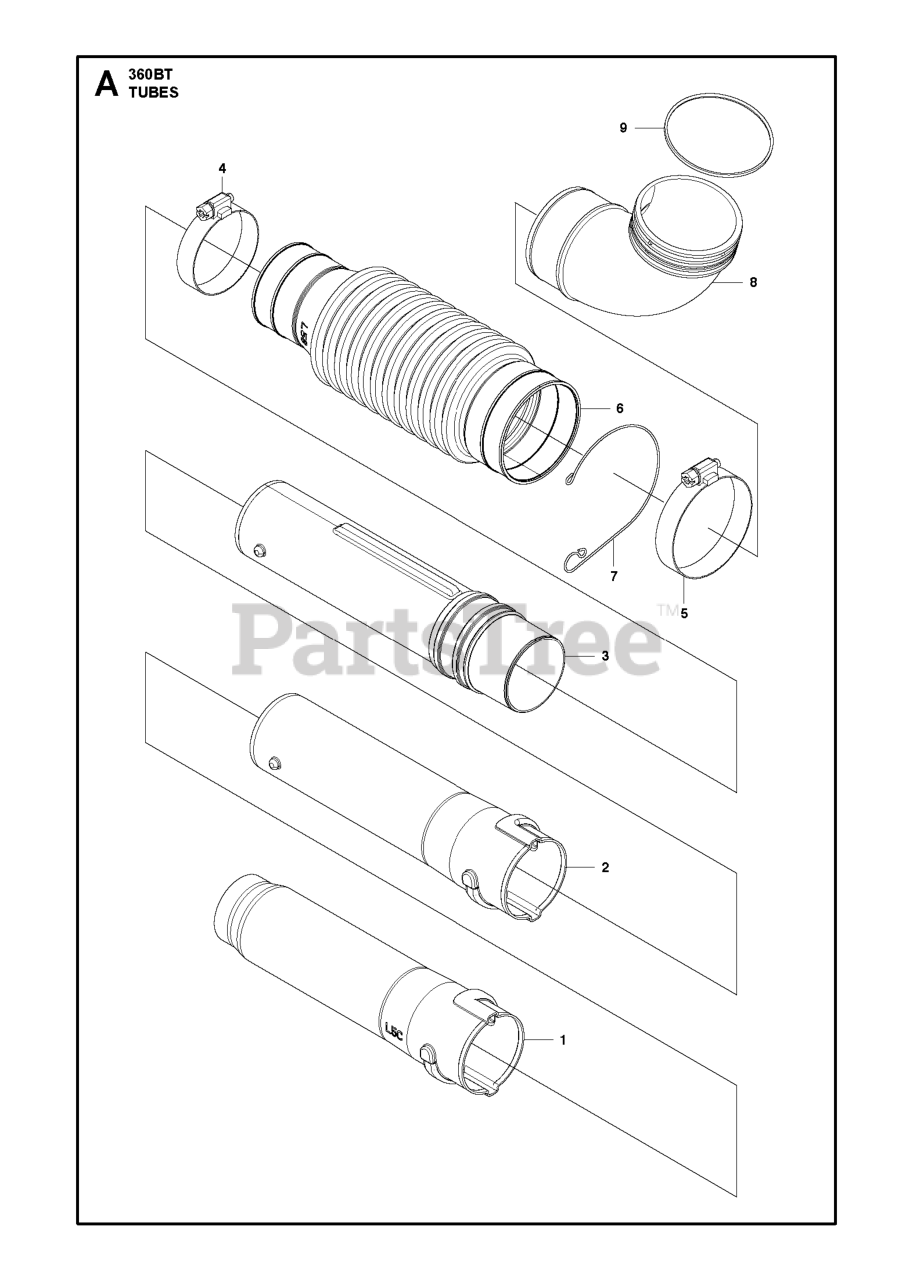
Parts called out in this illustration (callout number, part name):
3	SWIVEL JOINT
4	CLAMP(F96)
5	CLAMP(F115)
8	PIPE ELBOW
